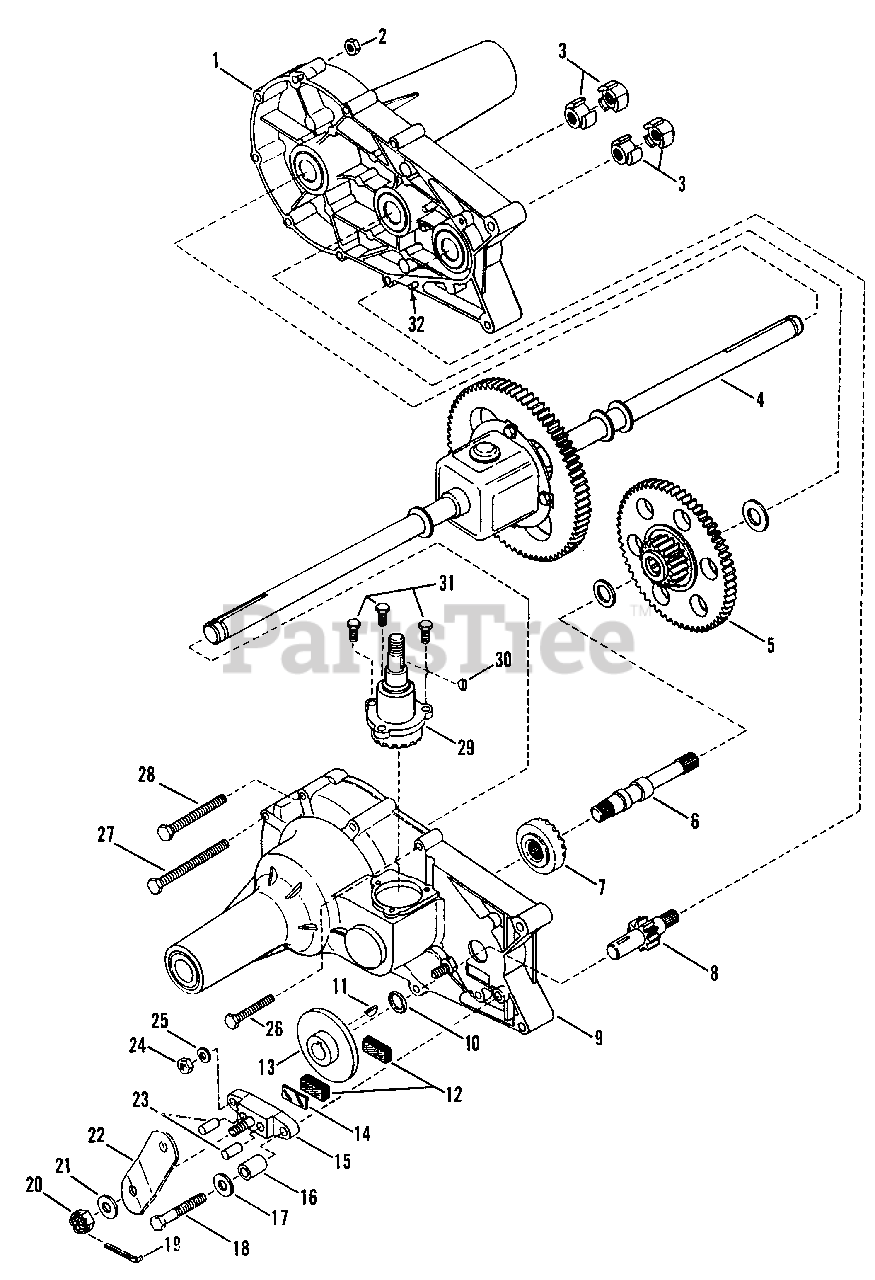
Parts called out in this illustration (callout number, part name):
1	TRANSAXLE ASSEMBLY HOUSING, L.H.
2	NUT, 5/16-18 Hex
3	PUMP COUPLING
4	DIFFERENTIAL ASSEMBLY
5	REDUCTION GEAR ASSEMBLY
6	SHAFT, Drive
7	GEAR, Drive Pinion
8	SHAFT, Pinion Gear
9	TRANSAXLE ASSEMBLY HOUSING, R.H.
10	SEAL, Grease
11	KEY, 3/16 x 5/8" Hi-Pro
12	PUCK, Brake
13	DISC, Brake
14	PLATE, Puck
15	BRAKE YOKE ASSEMBLY
17	WASHER, Flat, .265 I.D. x 7/8" O.D.
18	BOLT, 1/4-20 x 2" Hex
19	PIN, Cotter
20	NUT, 5/16-24 Castle
21	WASHER, Flat, .343 I.D. x .88" O.D.
22	ARM, Brake Actuator
23	PIN, Brake Actuating
24	NUT, 1/4-20 Hex
25	WASHER, 1/4 Spring Lock
26	BOLT, 1/4-20 x 2" Hex Hd., Self-Tapping
27	BOLT, 5/16-18 x 3 3/4" Hex Head
28	BOLT, 1/4-20 x 3" Hex Hd., Self-Tapping
29	INPUT PINION HOUSING ASSEMBLY
30	KEY, 3/32 x 5/8" Hi-Pro
31	SCREW, 1/4-20 x 3/4" Hex Head
32	PIN, Roll, 3/16 x 1.5"
